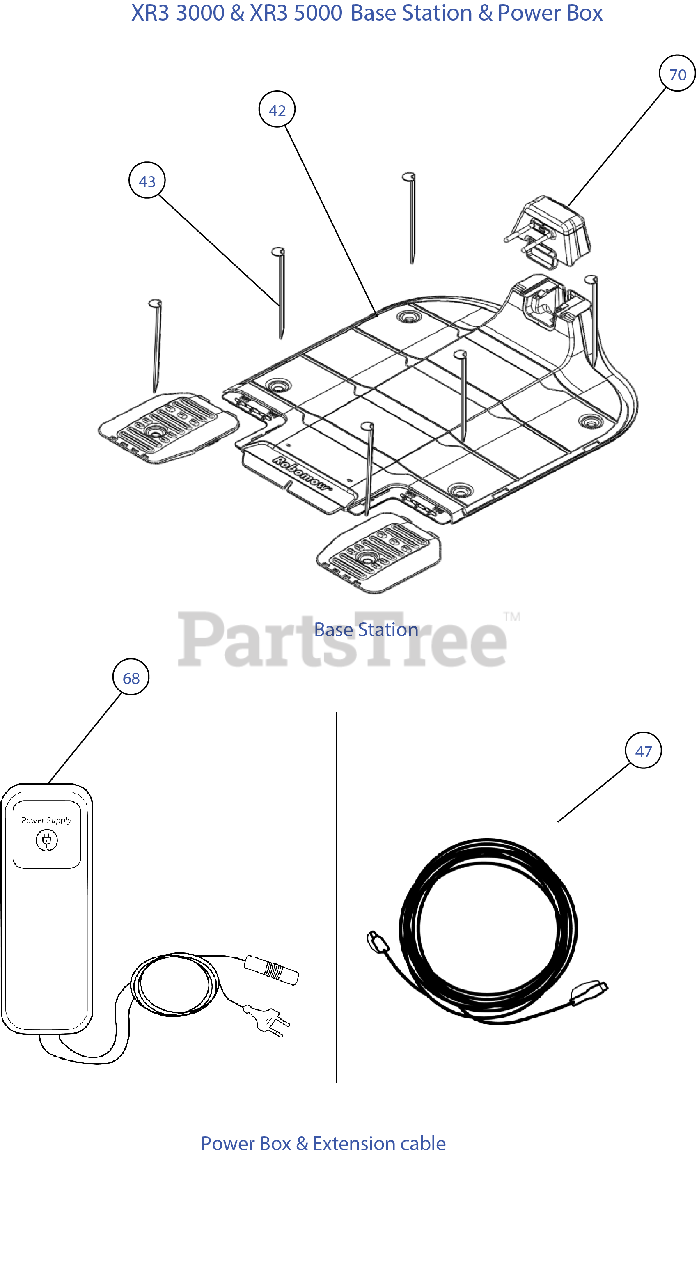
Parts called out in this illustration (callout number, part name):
42	BASE STATION W/O H
43	FASTENING STAKES-B
47	20M CABLE-PBOX TO STATION
68	POWER BOX
70	RS CHARGING ADAPTOR (2018)
